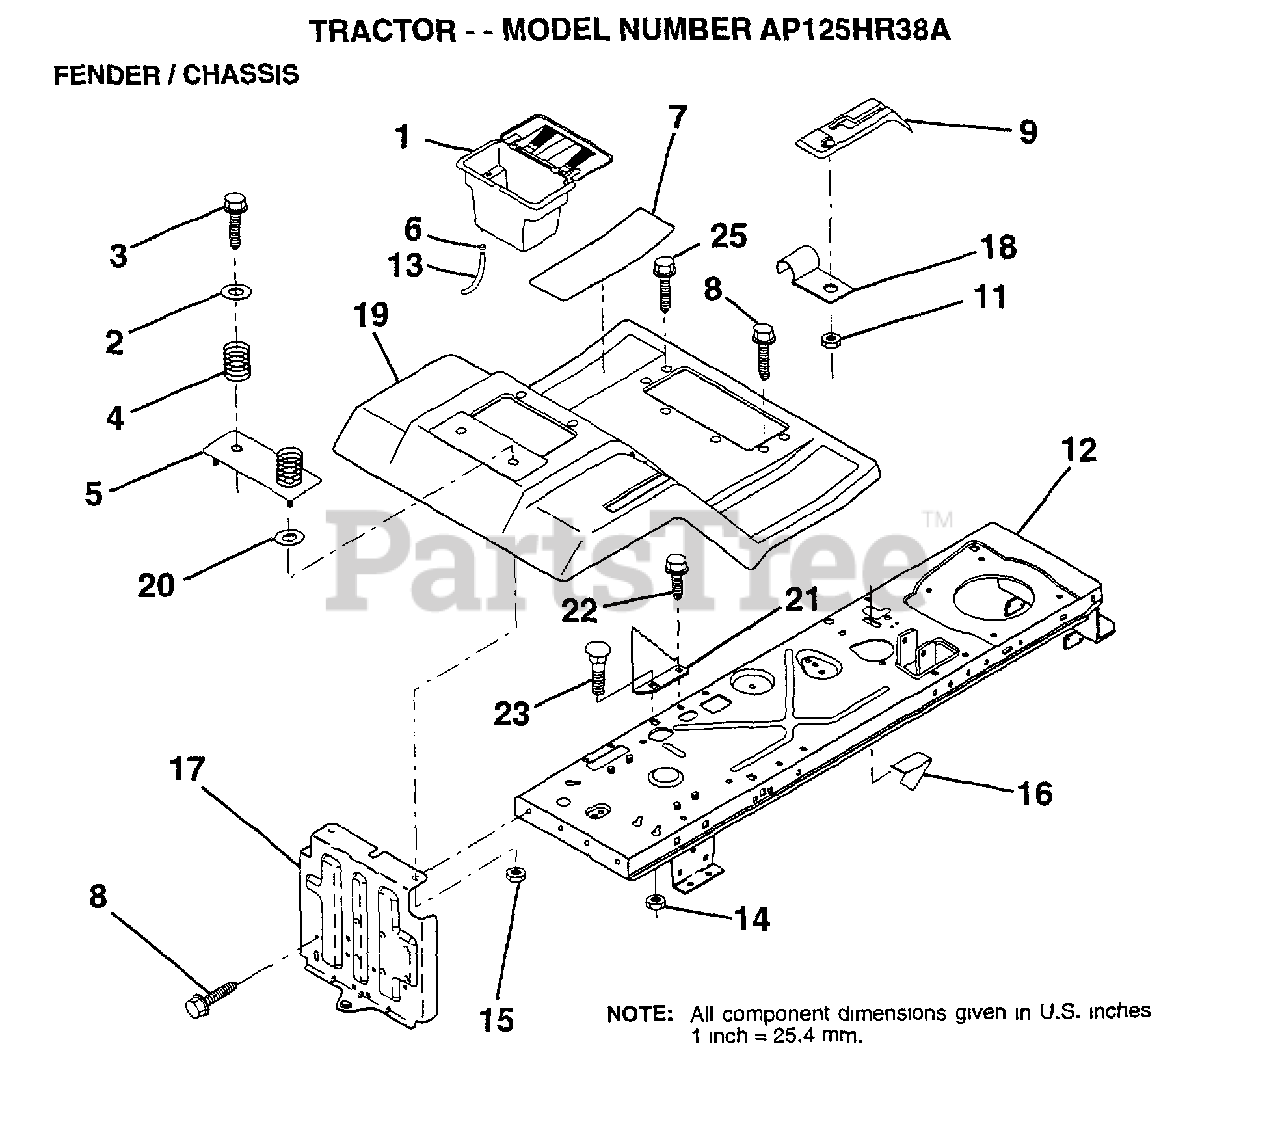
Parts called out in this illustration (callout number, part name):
2	WASHER
3	SCREW
4	SPRING COMPRESSIO
5	BTRY FENDER PLATE
6	HOSE CLAMP T
7	PAD FOOTREST
8	SCREW
9	CONSOLE.HYD.W/IGN
11	NUT
12	CHASSIS.WELD.ASM.
13	TUBE T
15	NUT HXKEP 1/4X20
17	DRAWBAR ASM LR
18	"CLIP,INSULATOR"
19	FENDER/FOOT MS505
21	BRACKET STOP DEPT
22	SCREW LT
25	SCREW
